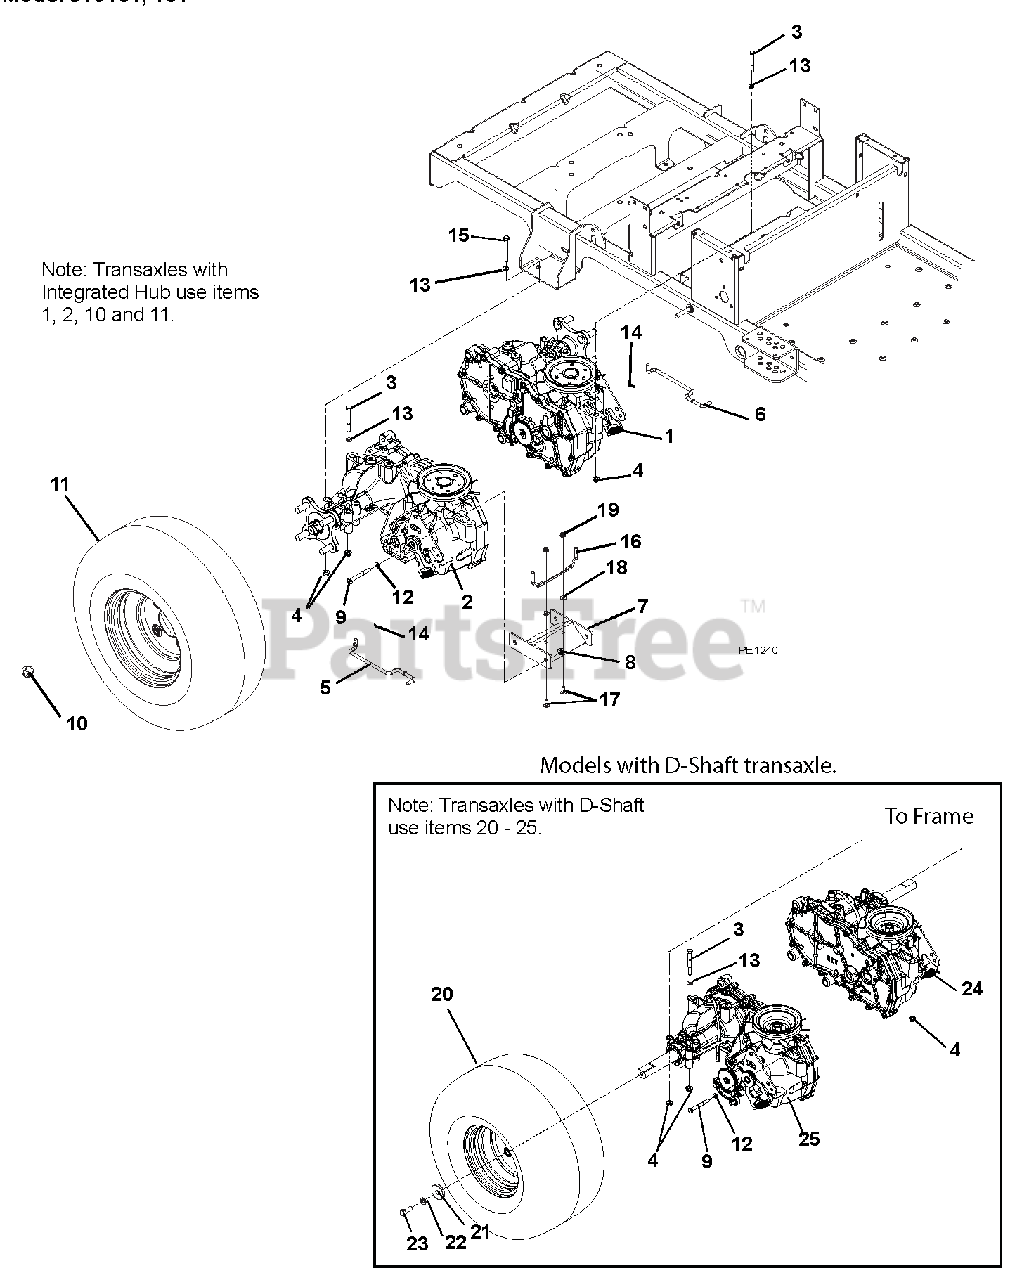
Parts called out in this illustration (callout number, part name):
1	TRANSAXLE, LH EZT SHORT
2	TRANSAXLE, RH EZT SHORT
3	@BLT-HEX .31-18X2.25 GR5 YWZC
4	@NUT-LK-NYL-FLG .31-18 YWZC
5	DUMPVALVE, RH LCZ
6	DUMPVALVE, LH LCZ
7	WMT, TRANSMISSION BRACE
8	@NUT-LK-NYL-FLG .38-16 YWZC
9	@BLT-HEX .38-16X2.50 GR5 YWZC
10	WHEEL NUT .500-20 YZ
11	TIRE-ASM 18X6.5-8 2 PLY OFFSET
12	WSHR-FL-STL .406X1.00X.188 YWZ
13	@WSHR-FL-STL.38X.875X.083 YWZC
14	PIN-HAIR INT .06X.18X.77
15	@BLT-HEX .31-18X2.75 GR5 YWZC
16	BELT FINGER, DRIVE SHEAVE
17	@BLT-RDHDSQNK .25-20X.75 G5YZ
18	@WSHR-FL-STL.281X.62X.065 YWZC
19	@NUT-LK-NYL-FLG .25-20 YWZC
20	TIRE-ASM 18X6.5-8 4 PLY DSHAFT
21	WSHR,FLT STL.406X1.50X.245YWZC
22	@WSHR-LK .38X.094 REG YWZC
23	@BLT-HEX .38-16X1.00 GR5 YWZC
24	TRANSAXLE, LH EZT D-SHAFT
25	TRANSAXLE, RH EZT D-SHAFT
